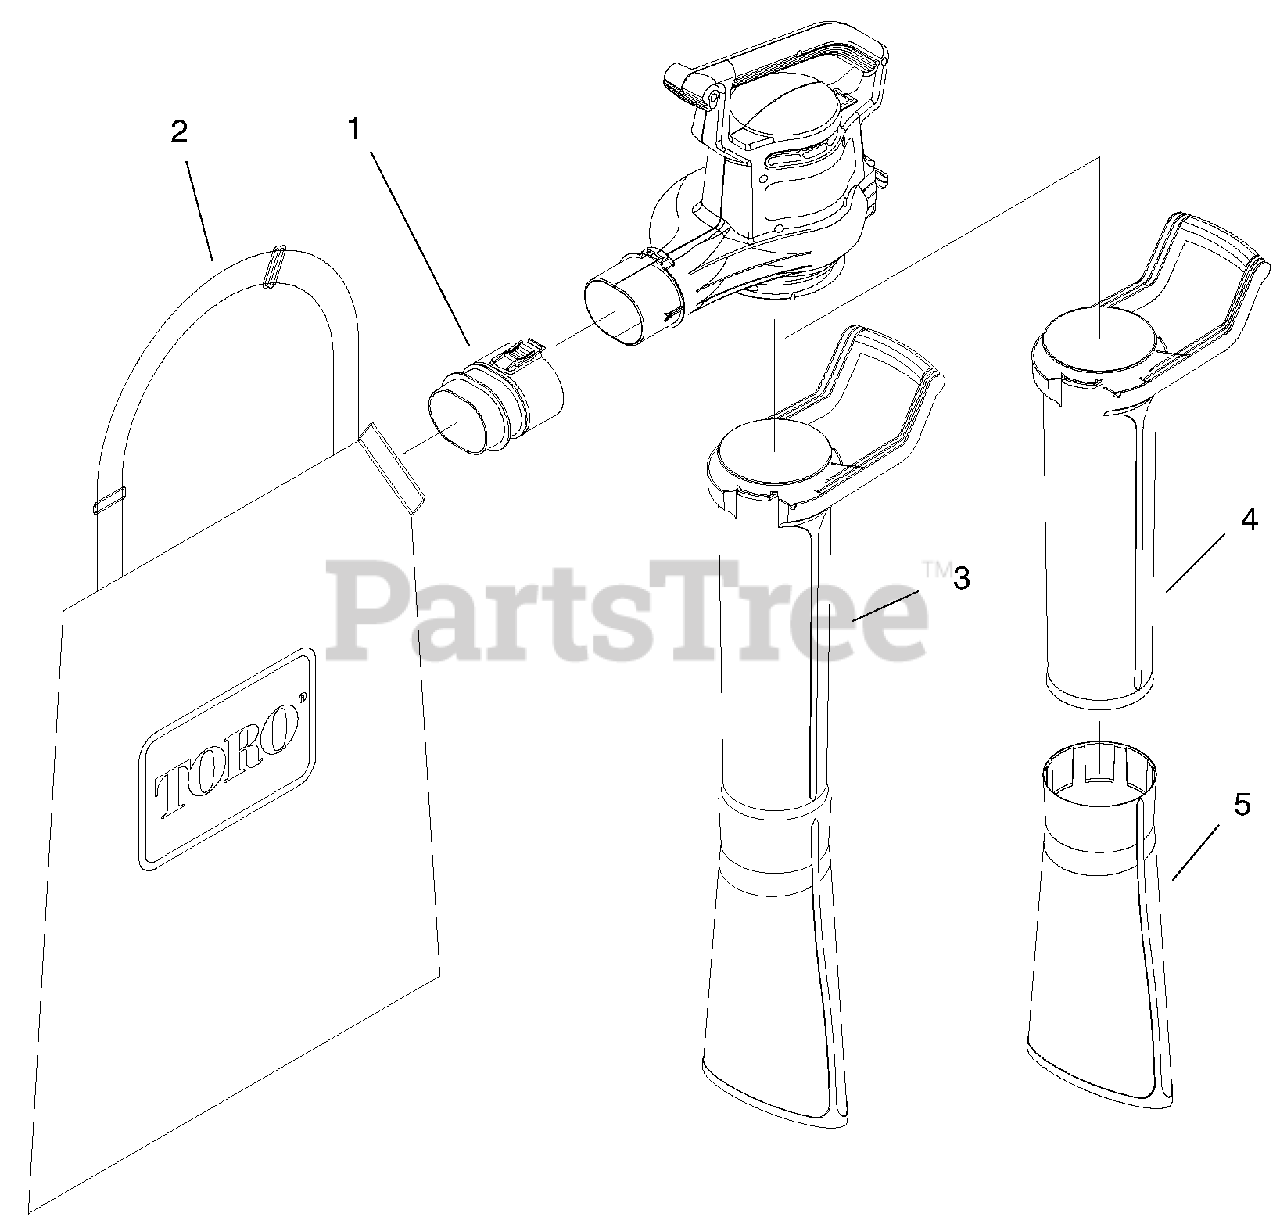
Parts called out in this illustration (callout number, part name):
1	Tube-Bag Inlet
2	Bag
3	Tube-Vac (Only On: 51566)
4	Tube-Vac (Only On: 51568)
5	Tube-Vac (Only On: 51568)
